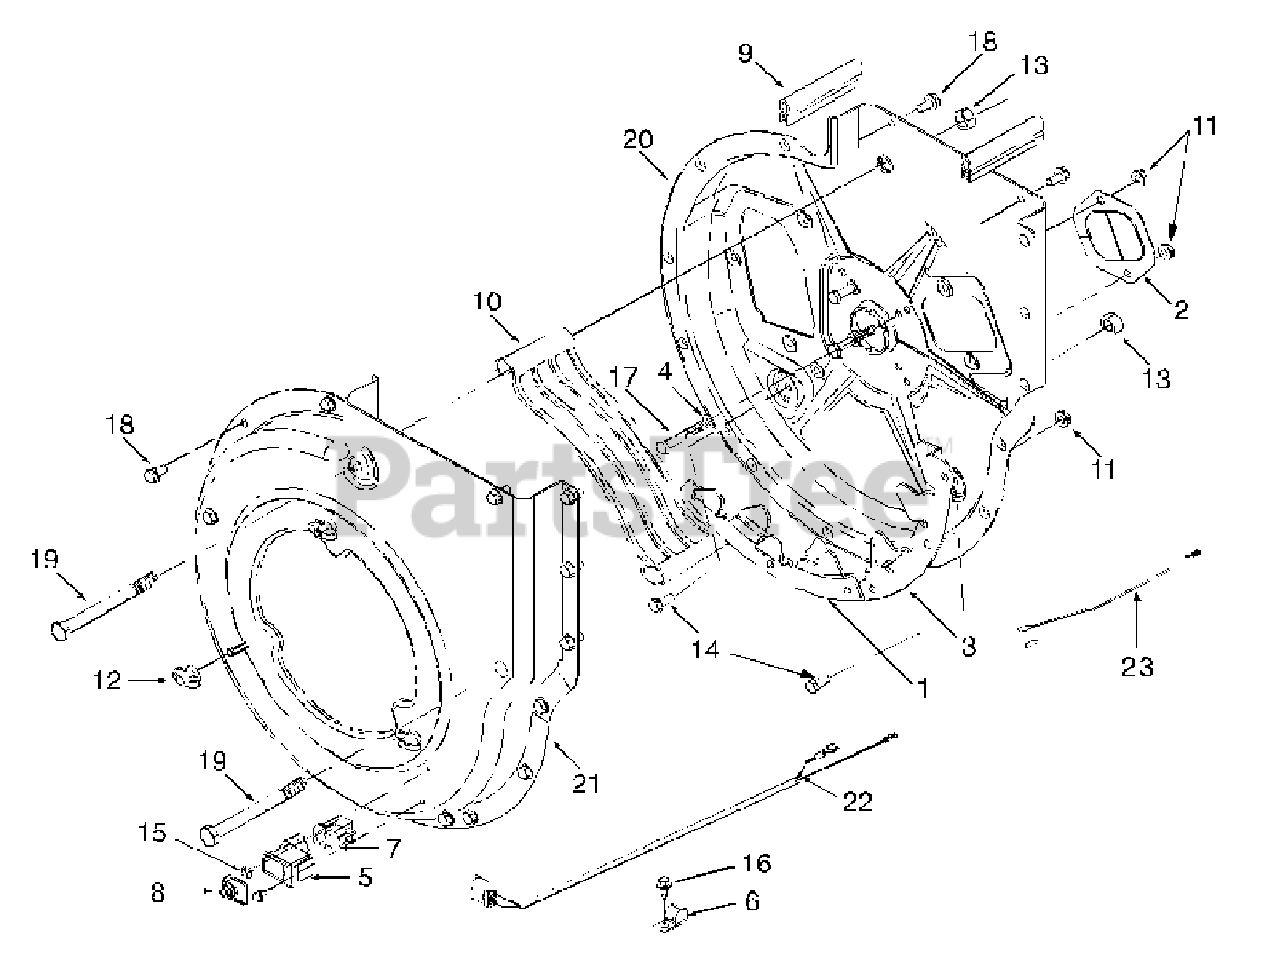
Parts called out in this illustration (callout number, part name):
1	Blade, Flail Housing
3	Blade, Upper Shredder
4	Washer, Lock, 5/16
5	Cover, Safety Switch Mtg
6	Clamp
7	Switch, Snap Mount
8	Cover, Switch
9	Rubber Seal
10	Screen, Discharge
11	Nut, Hex Flange Lock, 5/16-18
12	Knob, 5/16-18
13	Nut, Hex Center Lock, 1/2-13
14	Screw, Hex Cap, 5/16-18 x .75 GR5
15	Screw, Wash Hd Tapp #10-16
16	Screw, Wash Hd Tapp 1/4-141
17	Screw, Hex Cap, 5/16-18 x 2 GR5
18	Screw, Wash Hd Tapp 5/16-18
19	Screw, Hex Cap, 1/2-13 x 5.0
20	Housing Ass'y, Inner Flail
21	Housing Ass'y, Outer Flail
22	Harness, Wire
23	Adapter, Harness
